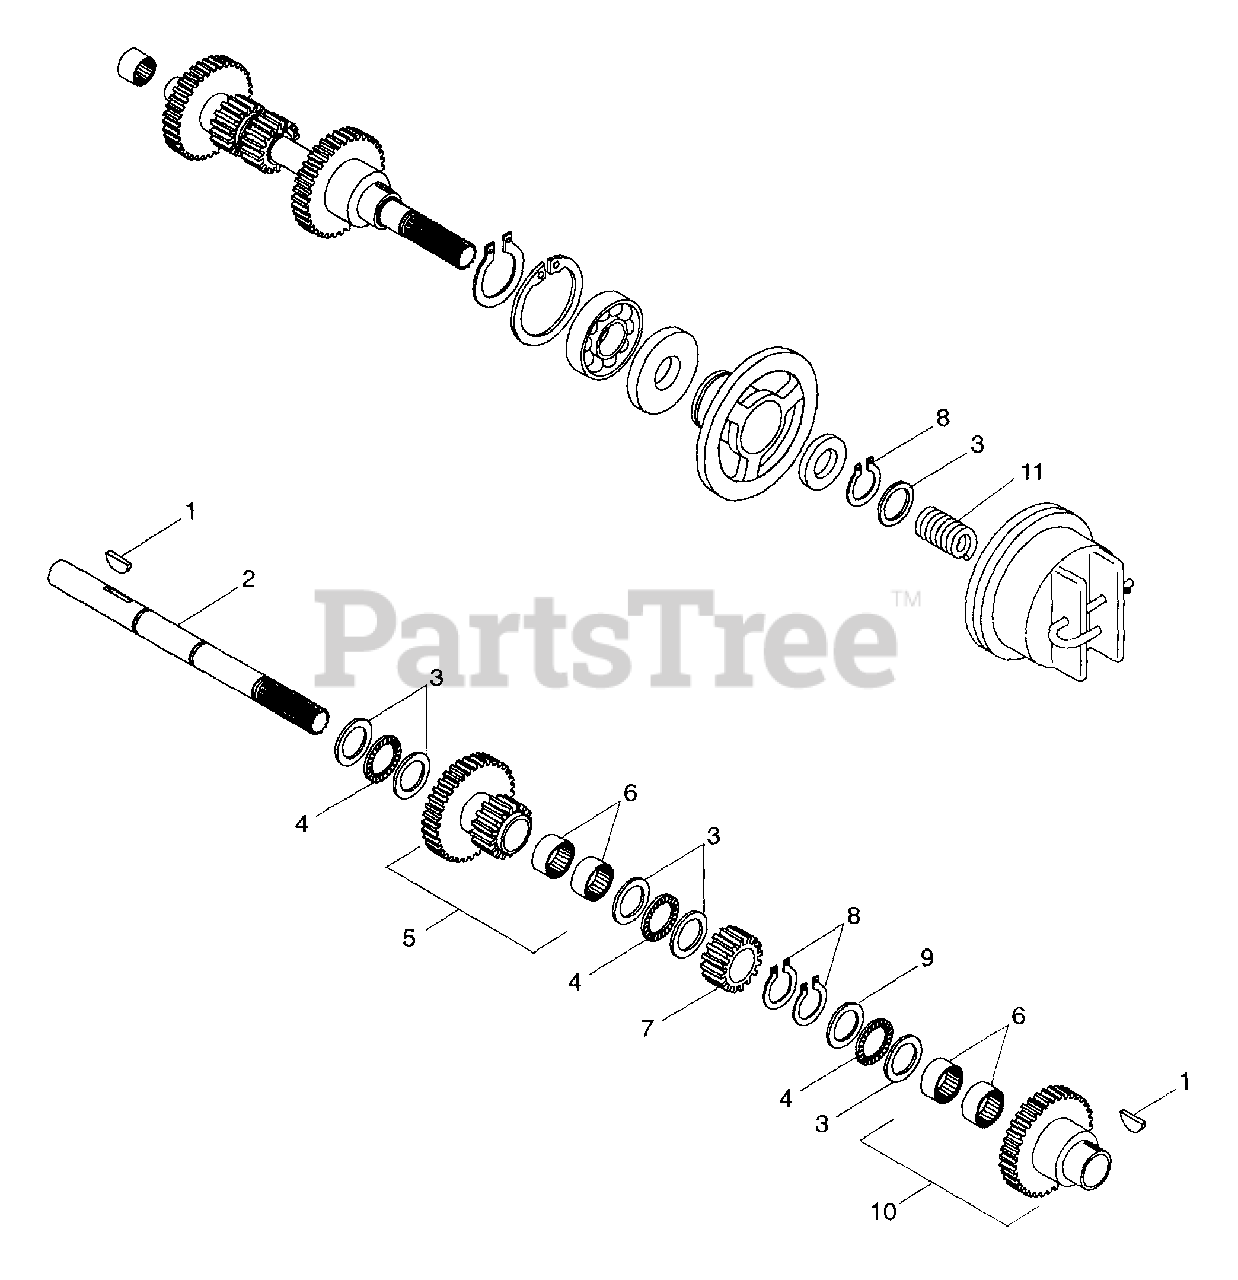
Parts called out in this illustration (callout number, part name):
1	Key, Woodruff .19 x .63
2	Shaft, Splined Reverse Clutch
3	Bearing-N-Thrust .752 x 1.24 x .031
4	Bearing-N-Thrust .754 x 1.24 x .078
5	Gear, Idler Assembly
6	Bearing-Roller .75 x 1.0 x .50
7	Gear, 10 DP 16 Teeth x .750
8	Ring-Retaining-Internal .750 x .042
9	Washer-Thrust .752 x 1.240 x .062
10	Assembly Reverse Gear & Bearing
11	Spring, Compression .085 x .80 x 1.00
